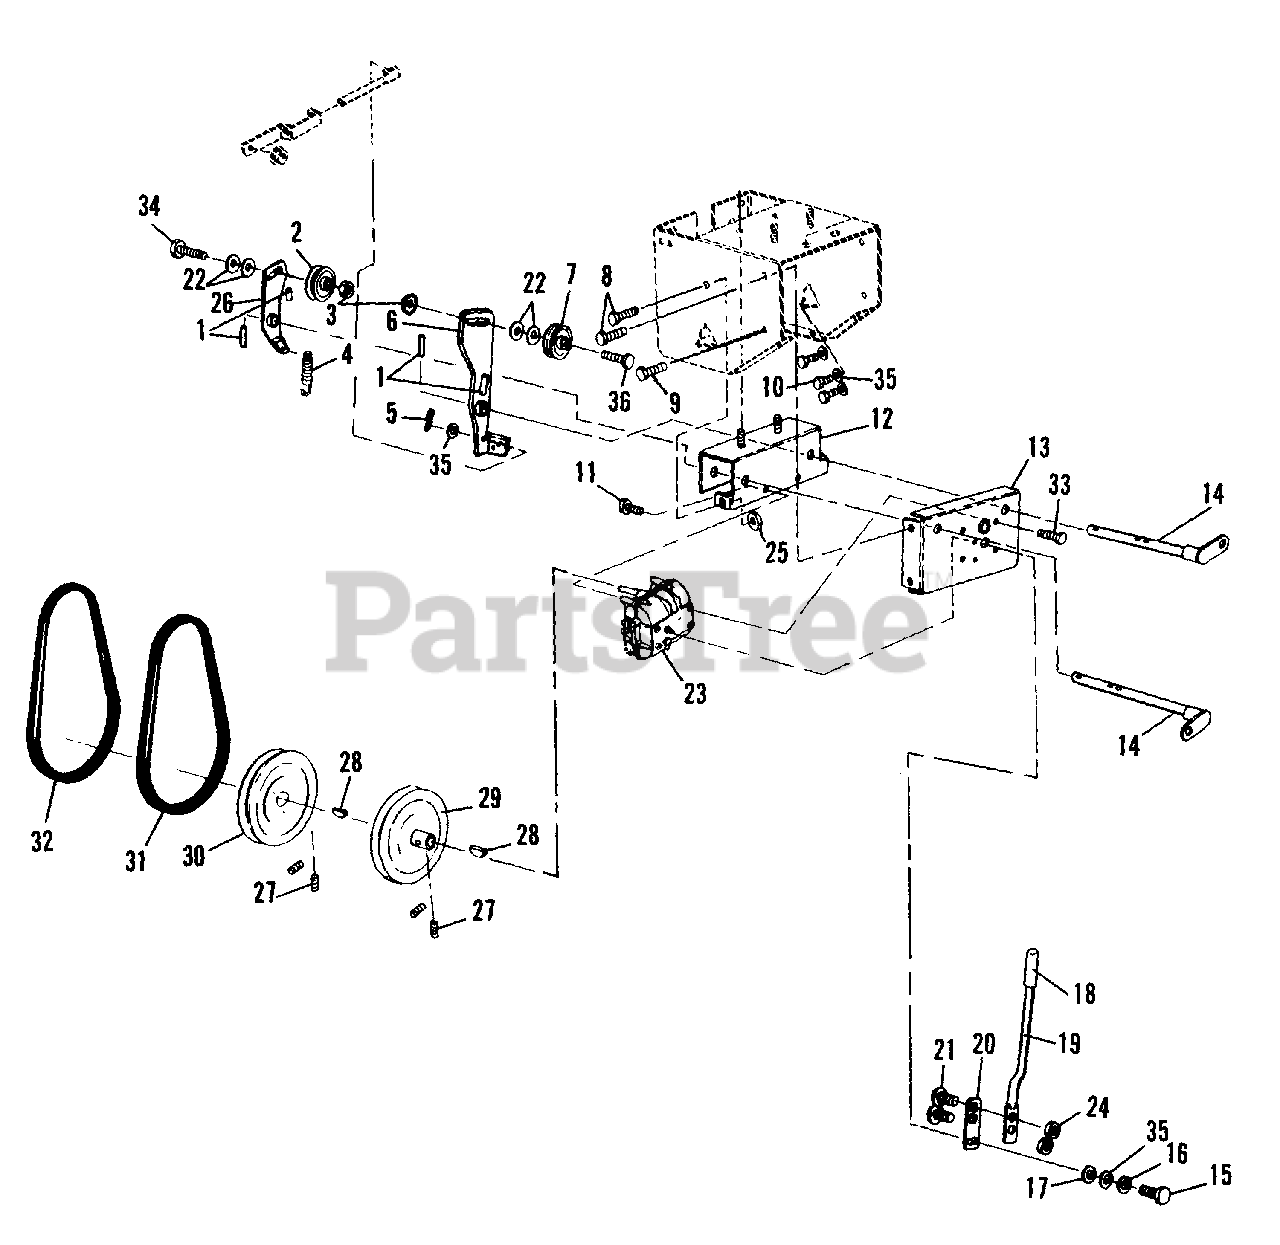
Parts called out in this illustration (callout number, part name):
2	IDLER PULLEY
3	NUT, Hex Centerlock Jam, 3/8-16
4	SPRING
5	PIN, Cotter
6	IDLER ARM & BRAKE ASSEMBLY
7	IDLER PULLEY
8	SCREW, Flange Lock, 5/16-18 x 5/8
9	SCREW, Hex Head Taptite, 5/16-18 1/2
10	CAPSCREW, Hex Head, 1/4-20 x 3/4
11	CAPSCREW, Hex Head, 5/16-18 x 5/8
12	TRANS. SUPPORT ASSEMBLY
13	TRANSMISSION MOUNTING PLATE
14	ROD ASSEMBLY
15	CAPSCREW, Hex Head, 1/4-28 x 1/2
16	LOCKWASHER, 1/4
18	GRIP, Lever
19	LEVER, Drive Control
20	SHIFT PLATE
21	CARRIAGE BOLT, 1/4-20 x 5/8
23	TRANSMISSION, 3 Speed Peerless
24	NUT, Hex, Centerlock, 1/4-20
25	NUT, Hex, Centerlock, 5/16-18
26	IDLER ARM ASSEMBLY
27	SETSCREW, Square Head, /516-18 x 3/4
28	KEY, Hi-Pro
29	TRANSMISSION PULLEY
30	AUGER DRIVE PULLEY
31	V-BELT, Transmission Drive
32	V-BELT, Auger Drive
33	SCREW, Hex Head Taptite, 5/16-18 x 5/8
34	CAPSCREW, Hex Head, 3/8-16 x 1-3/8
35	WASHER, 1/4
